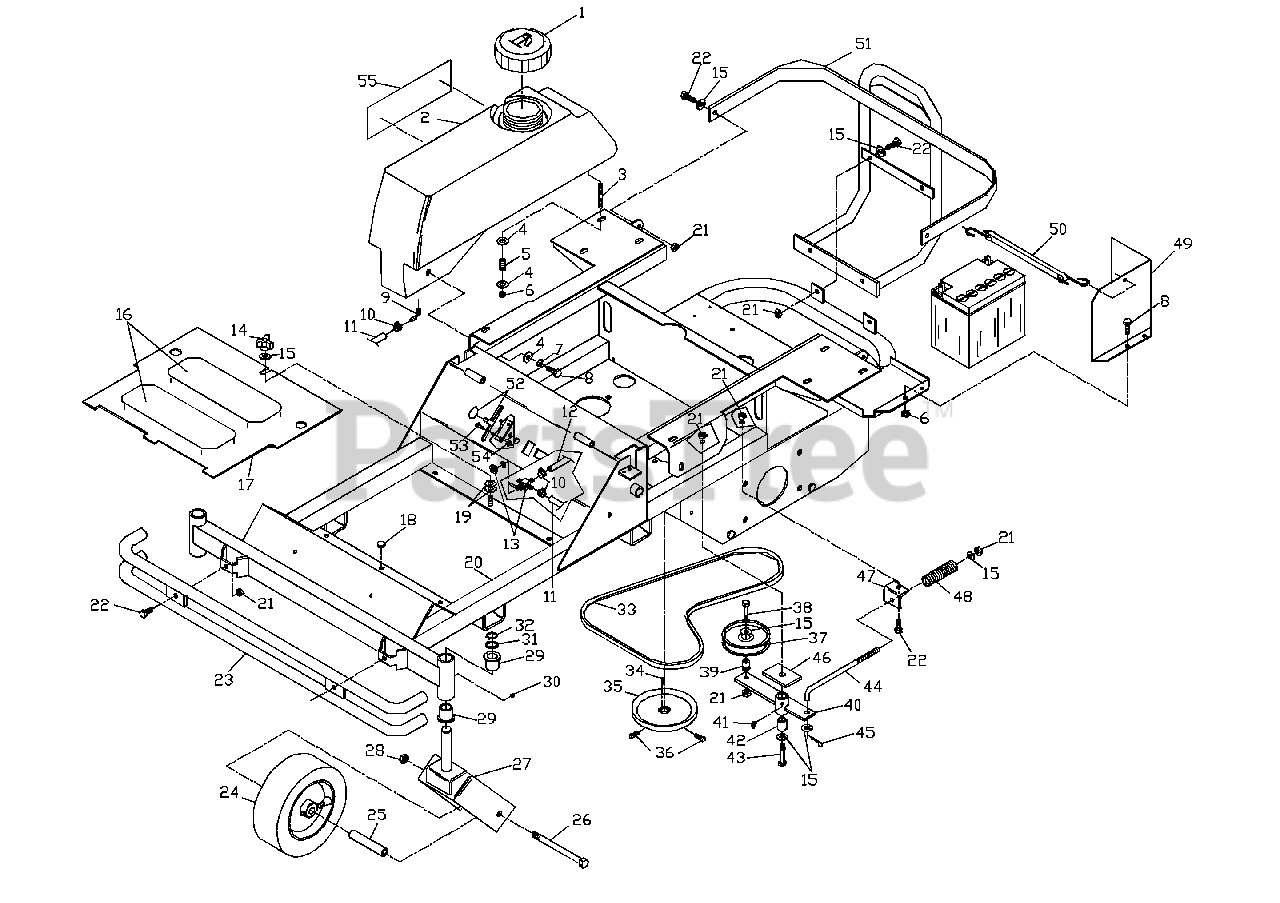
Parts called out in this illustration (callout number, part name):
1	FUEL CAP
2	FUEL TANK RT.
3	5/16C STUD
4	5/16 FLAT WASHER
6	NUT 5/16C CENTERLOCK
7	5/16 LOCKWASHER
8	HCS 5/16C X 3/4
9	90 DEG. HOSE BARB
10	HOSE CLAMP
11	FUEL LINE, TANK
12	FUEL LINE, ENGINE
13	FUEL VALVE
15	3/8 FLAT WASHER
16	ANTI-SKID PAD
17	FOOTPLATE
18	BUMPER, RUBBER
19	3/8 DISC WASHER
20	FRAME W/DECALS
21	NUT 3/8C CENTERLOCK
22	HCS 3/8C X 1
23	BUMPER, FRONT
24	CASTER TIRE
24	ROLLER BEARING 1"
24	ZERK
24	FLANGED BEARING
24	ROLLER BEARING 2 1/4"
26	HCS 1/2C X 5 1/2
27	YOKE WELDMENT
28	NUT 1/2C NYLOC
29	FLANGE BUSHING
31	MACHINERY BUSHING
32	7/8" RETAINING RING
34	KEY 5 MM SQ. X 25 MM
36	5/16C X 5/8 SQ. HEAD
37	IDLER PULLEY
38	HCS 3/8C X 1 3/4
39	IDLER FLANGE BUSHING
40	IDLER ARM WELDMENT
41	45 DEG. ZERK
42	PIVOT BUSHING
43	HCS 3/8C X 3
44	TENSION ROD
45	COTTER PIN
46	SUPPORT PLATE
47	TENSION BRACKET
48	COMPRESSION SPRING
49	BATTERY GUARD W/DECALS
50	BATTERY STRAP
51	ENGINE GUARD W/DECALS
52	THROTTLE CABLE
53	#10-24 X 1/2 HCS
54	#10-24 NYLOC NUT
55	DECAL, ZTH 4818
55	DECAL, ZTH 4820
55	DECAL, ZTH 4821
56	HCS 3/8C X 2 1/4 GD5
57	WEIGHT BLOCK
58	CHOKE CONTROL
